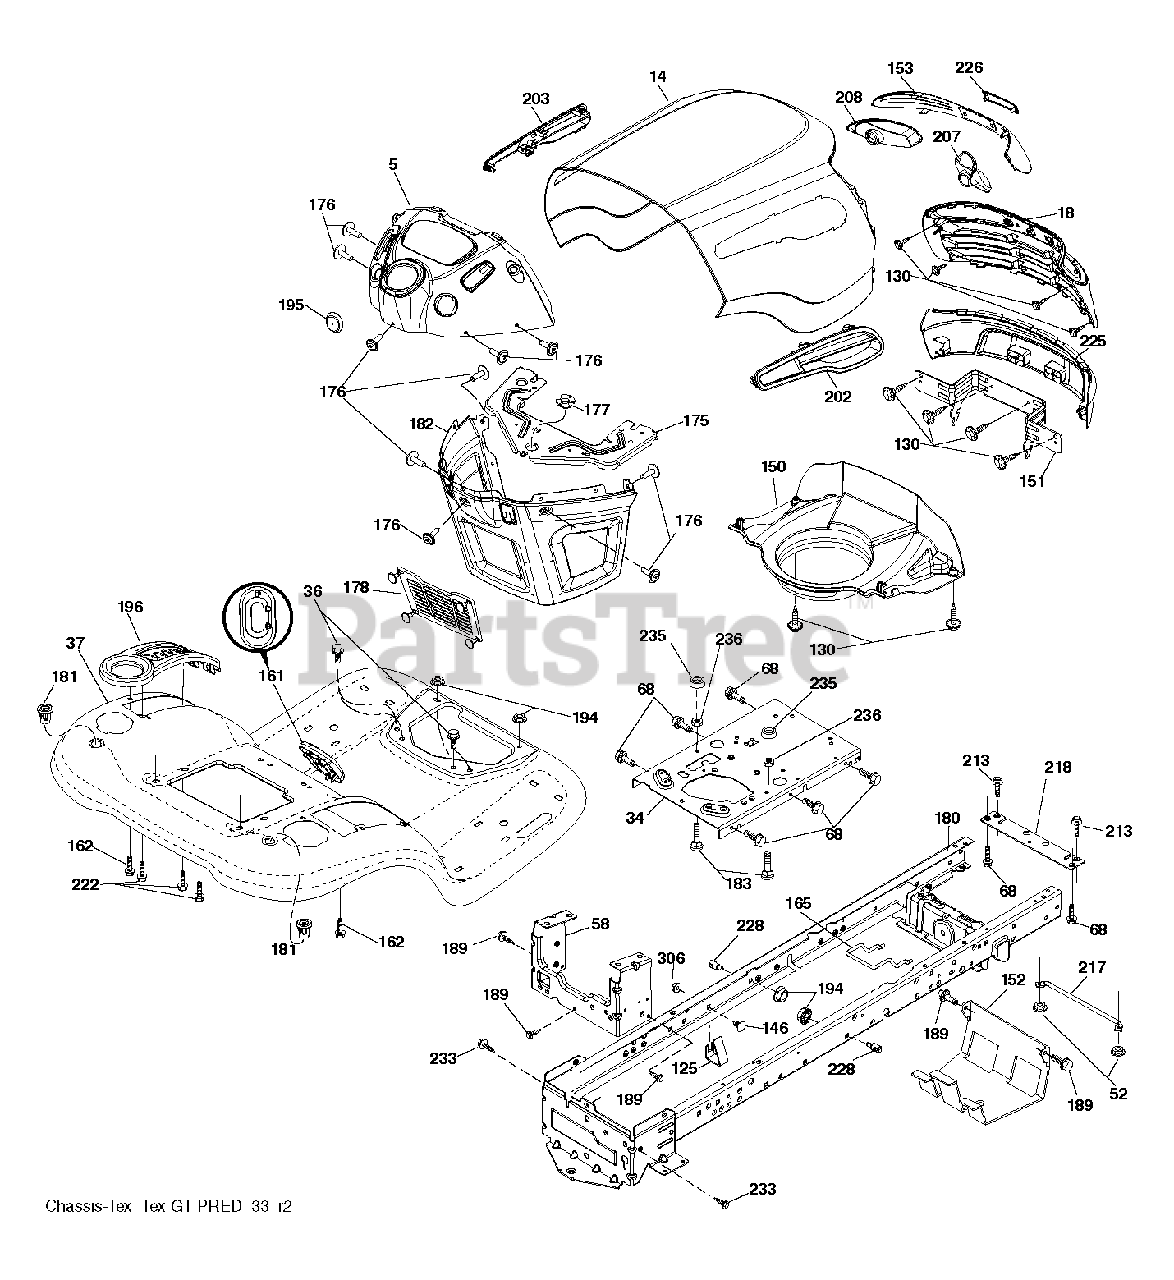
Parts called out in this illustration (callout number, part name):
36	SCREW 5/16"
52	LOCKNUT
58	DRAWBAR.UPPER.2PC,LRG.FENDER
125	Fuel Line Clip
130	SCREW.#10 X 0.750.BOS THREAD
146	BOLT.RDHD.SHT.SQNK.3
150	PREDATOR.YT.GT.HOOD.A
152	SHIELD BROWNING
161	CONSOLE.FUEL.WINDOW.STGT.BLACK
162	SCREW.HI-LO.CONSOLE
165	SUPPORT.TANK.REAR.W/TE
175	PLATE.CROSSMEMBER.HUSQ
176	SCREW.#10-24X5/8.RN.QU
177	BUSHING,STEERING
178	CARGO.ASM.NET.TXGT.W/C
180	CHASS.WLDMNT.TLT.12GA/2PC.20"
181	FEND/FTRST.PCH.CPH.NFW
182	DASH.LOWER.COMMON.12V.ADAPTOR
183	BOLT.5/16-18X1-1/4 FULL THD
189	SCREW
194	NUT LOCK HEX FLANGE 5/16-18
195	PLUG.HOLE.DASH.LOWER.12V.BLK
213	BOLT
217	ROD.PIVOT.HOOD
218	X-PIECE.HOOD.STOP.NON/
222	SCREW.1/4-20X5/8
228	STUD.FASTNER.W/ANTI-ROTATE
233	BOLT.SHOULDER
235	SPACER FENDER
236	NUT.CENTERLOCK.5/16-
306	NUT LOCK FLG 3/8-16 UNC
